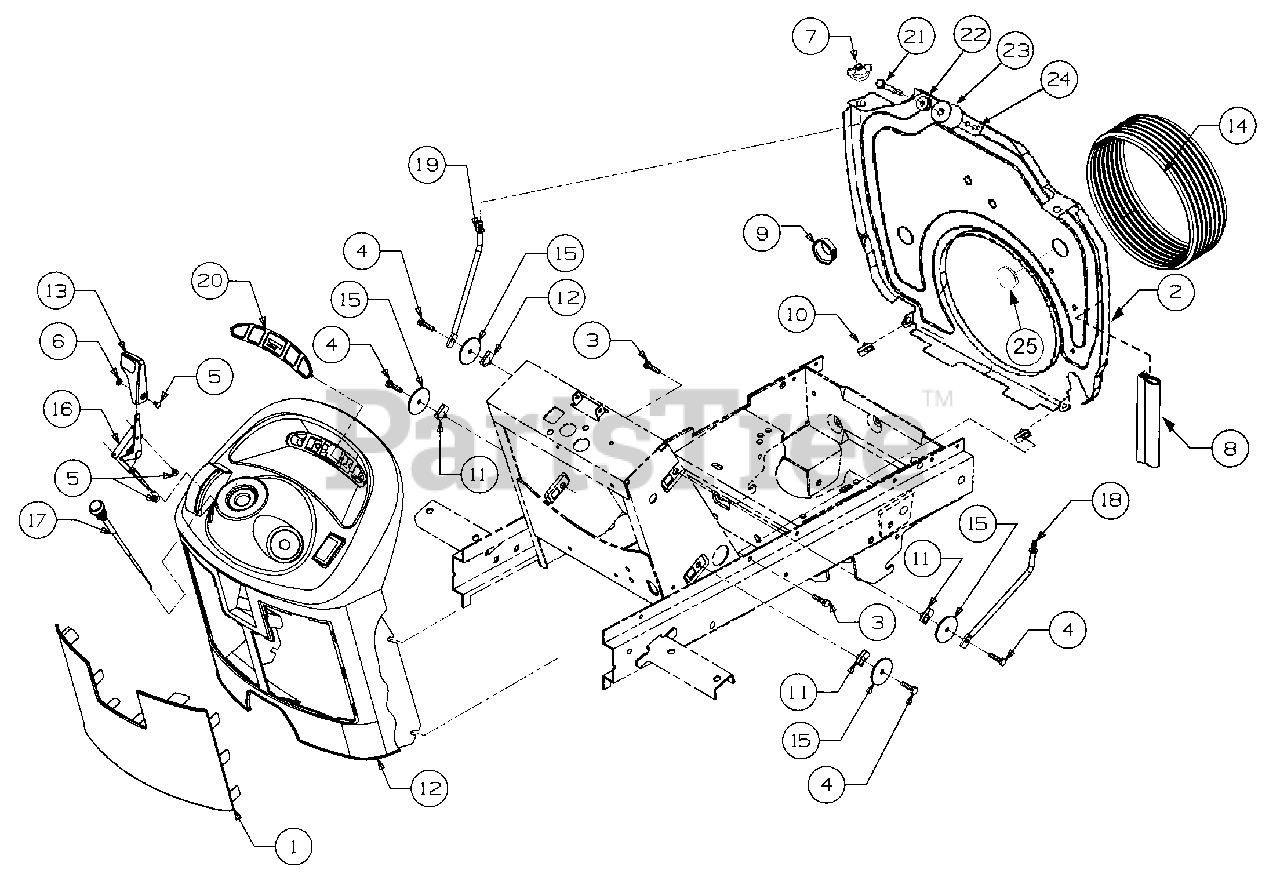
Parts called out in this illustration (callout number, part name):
4	Screw, Hex Cap, 1/4-20 x 1.0
5	Screw, Cross Rec Trus, #8-32 x .38
6	Nut, #8-32
7	Nut, Wing w/Bell Washer 1/4-20
8	Seal, Push On Trim
9	Bushing, Snap, 7/8 ID
10	Nut, U-Type Speed, 1/4-20
11	Nut, U-Clip, 1/4-20
12	Panel, Dash
13	Knob, Throttle
14	Boot, Intake
15	Washer, Flat, .285 x 1.75 x .10
16	Control, Throttle
17	Control, Choke
18	Rod, RH Mounting
19	Rod, LH Mounting
20	Label, Dash
21	Screw, Hex Cap,1/4-20 x 1.75 GR5
22	Washer, Flat, .283 x .75 x .030
23	Roller, Hood Latch
24	Nut, Hex Sems, 1/4-20
25	Plug. Button
